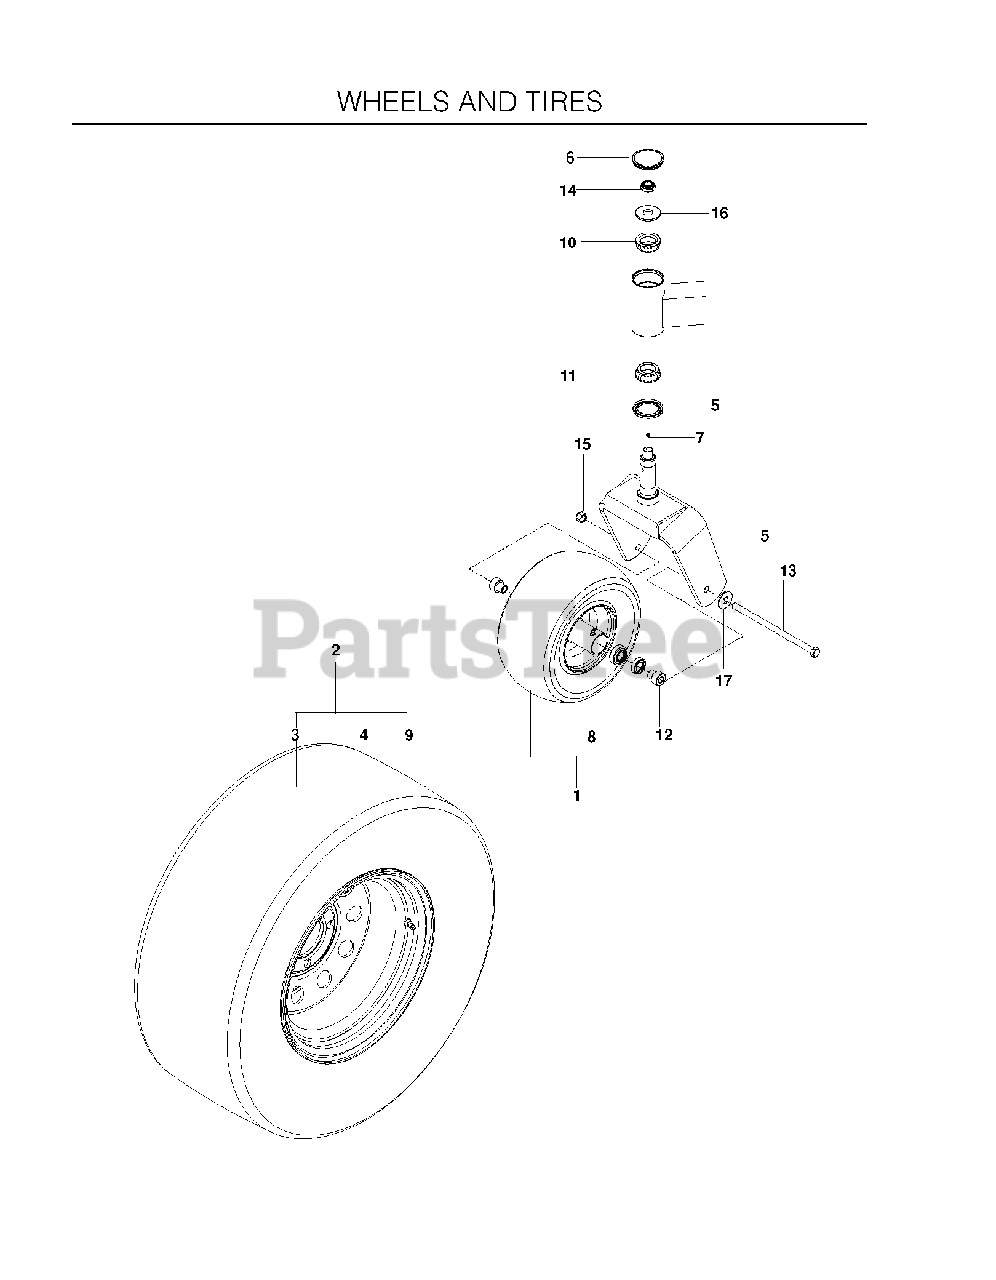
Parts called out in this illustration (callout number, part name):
1	TIRE, 13 X 6.5-6 NO FLAT
2	WHEEL, DRIVE, 26 X 12
3	TIRE, 26-12 X 12
4	RIM, 12 X 8.5, CENTERED
6	CAP, DUST
8	ZERK
9	VALVE STEM TR-412
10	CONE, LM67048
11	SEAL, BEARING
12	AXLE SPACER
13	HEX SCREW 1/2-13 X 9.5 GR5
14	NUT, 3/4-16 HEX THIN NYLOC ZD
15	NUT, 1/2-13 HEX FLG NYLOC ZD
16	WASHER, 3/4 HARDENED
17	WASHER 1/2" FLAT
